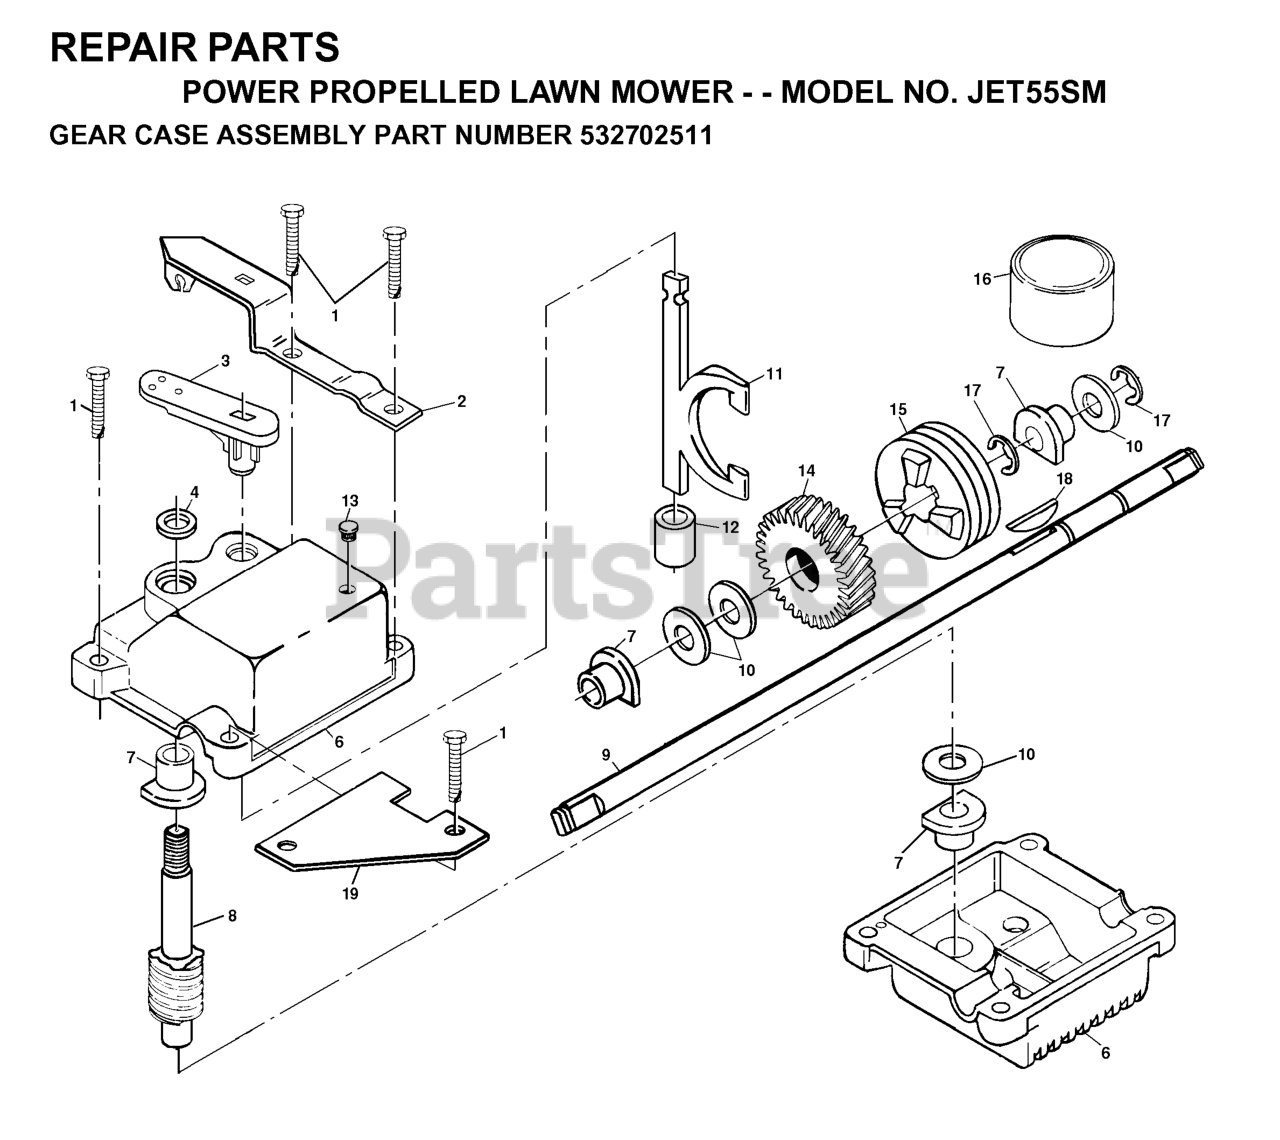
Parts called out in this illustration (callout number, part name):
1	SCREW
2	BRACKET
8	WORM SHAFT
9	DRIVE SHAFT, 20-5/8"
10	THRUST WASHER
11	YOKE.VIBRATORY FINISH.
13	PLUG.AUGER.GEAR.BOX.SNOW
14	GEAR.HELICAL
15	CLUTCH JAW
16	GREASE
18	HI PRO KEY
19	BRACKET SPRING
20	WOODRUFF KEY
21	WORM
